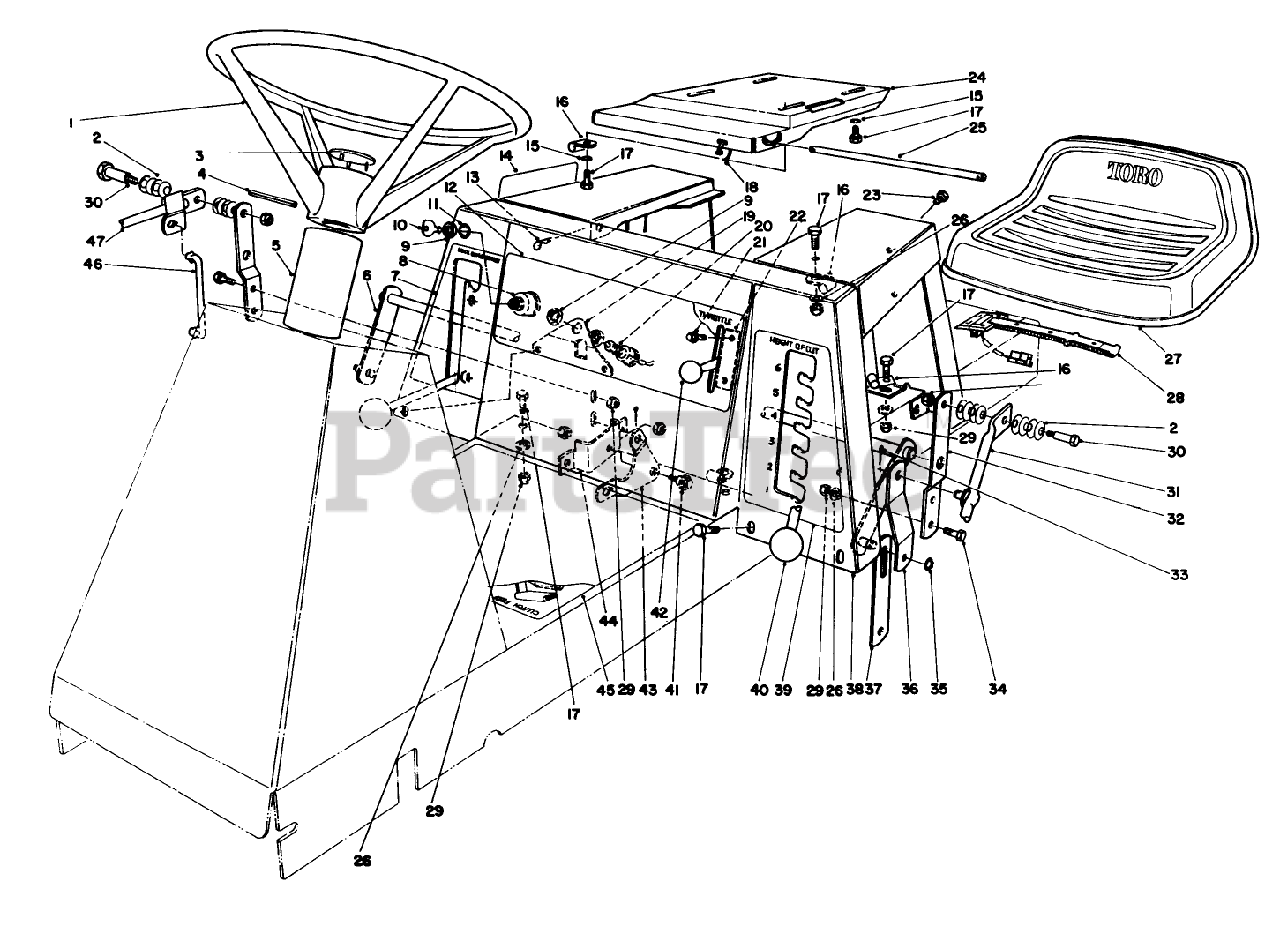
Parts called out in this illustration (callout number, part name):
1	STEERING WHEEL ASM
2	WASHER-BELLEVILLE
4	PIN-ROLL
5	STRG. SHAFT COVER
8	SWITCH-STARTER
9	NUT-HH
11	WASHER-LOCK
15	WASHER-LOCK
16	CLAMP
17	SCREW-HH
18	TIE-CABLE
19	SWITCH MT BRKT
20	DECK SWITCH
21	SCREW-HWHTF
22	THROTTLE CONTROL
23	SCREW-HH
25	SEAT BASE ROD
26	WASHER-PLAIN
28	SWITCH-SEAT
29	NUT-LOCK, NI
30	BOLT-SHOULDER
31	HOC LEVER WA *B
33	PIN-COTTER
34	SCREW-HH
35	RING-RETAINING
39	HOC DECAL
41	SCREW-SHOULDER
43	DECK ENGAGE BELLCRANK
46	BELLCRANK LINK(PLTD)
